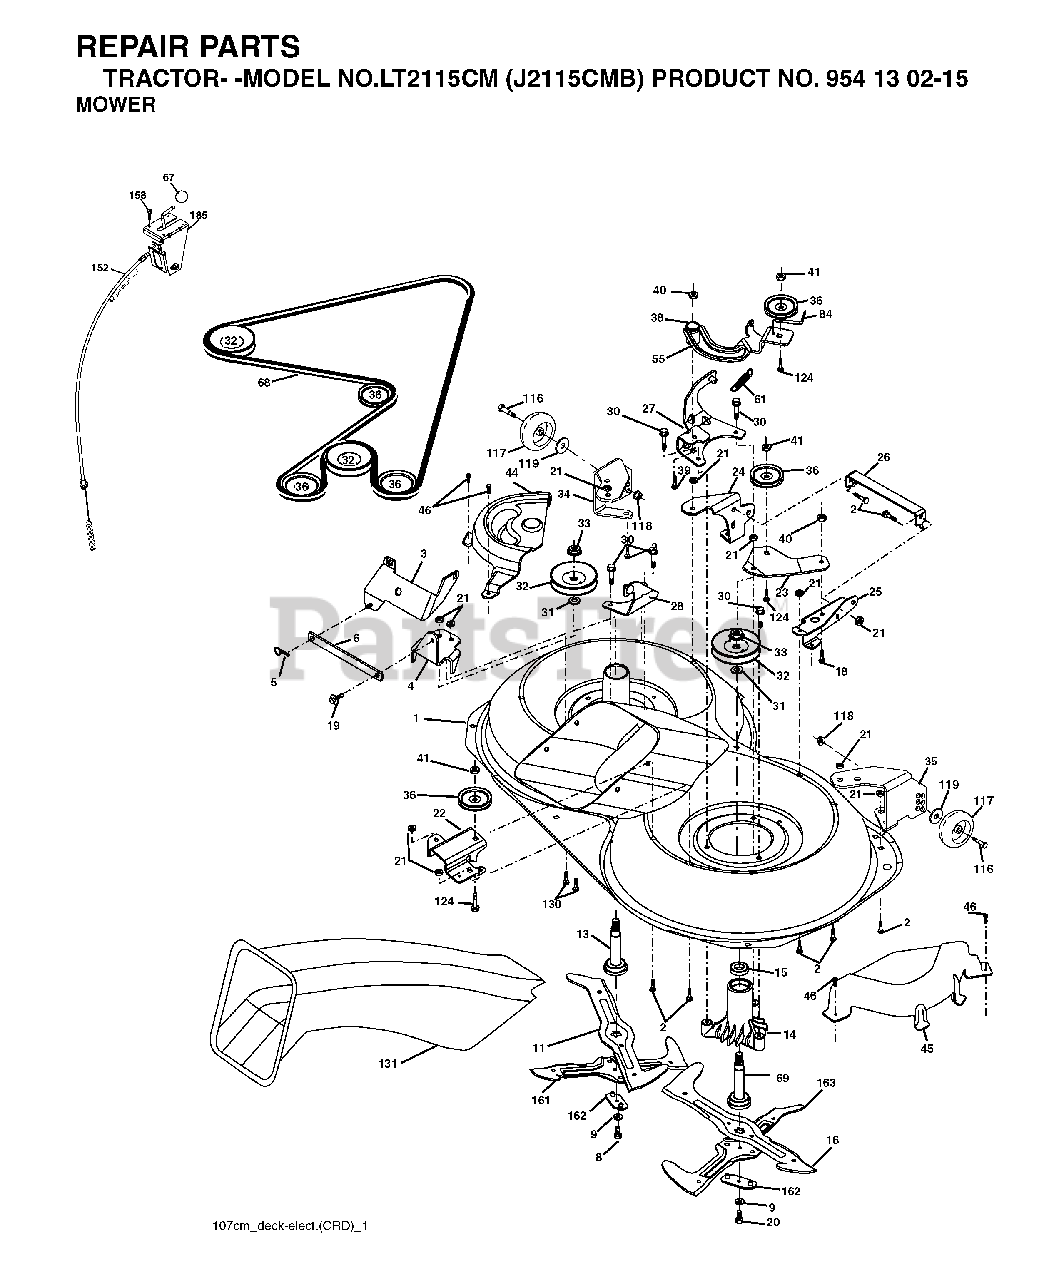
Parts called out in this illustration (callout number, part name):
1	MOWER HOUSING, DECK
2	BOLT
3	BRACKET
5	RETAINER-SPRNG RB
6	BAR SWAY
9	LOCKWASHER
13	SHAFT ASM VENT
14	HSG MANDREL
19	BOLT SHD 5/16-18
21	LOCKNUT
24	BRACKET
25	BRACKET
26	BRACE
28	BRACKET
30	SCREW, WASHER HEAD
31	WASHER.SPACER.MANDREL
32	PULLEY, MANDREL
33	NUT, FLG TOPLOCK 9/16"
36	PULLEY.IDLER.4.25
38	SPACER.RETAINER.MOWER
39	BOLT.3/8-14X1.25
40	LOCKNUT
45	MANDREL COVER
46	SCREW.1/4-20X5/8
55	ARM IDLER
61	SPRING.TENSION.BELT
67	KNOB T (3/8 HOLE)
68	HEX-BELT
69	SHAFT.ASM.W/LWR.BRG.RH.THREAD
84	KEEPER, BELT IDLER
116	SHOULDER BOLT
117	WHEEL GAGE DONUT
118	LOCKNUT
119	WASHER
124	BOLT.3/8-16X1.50
131	CHUTE BAGGER
151	BRACKET, CLUTCH CABLE
153	WASHER FLAT 3/8"
154	SPRING RETAINER
155	SPRING RETENTION LEVER
156	SPACER CLUTCH CABLE
157	ROD CLUTCH CABLE 3/8"
158	SCREW
185	HEAD ASM. CABLE CLUTCH
